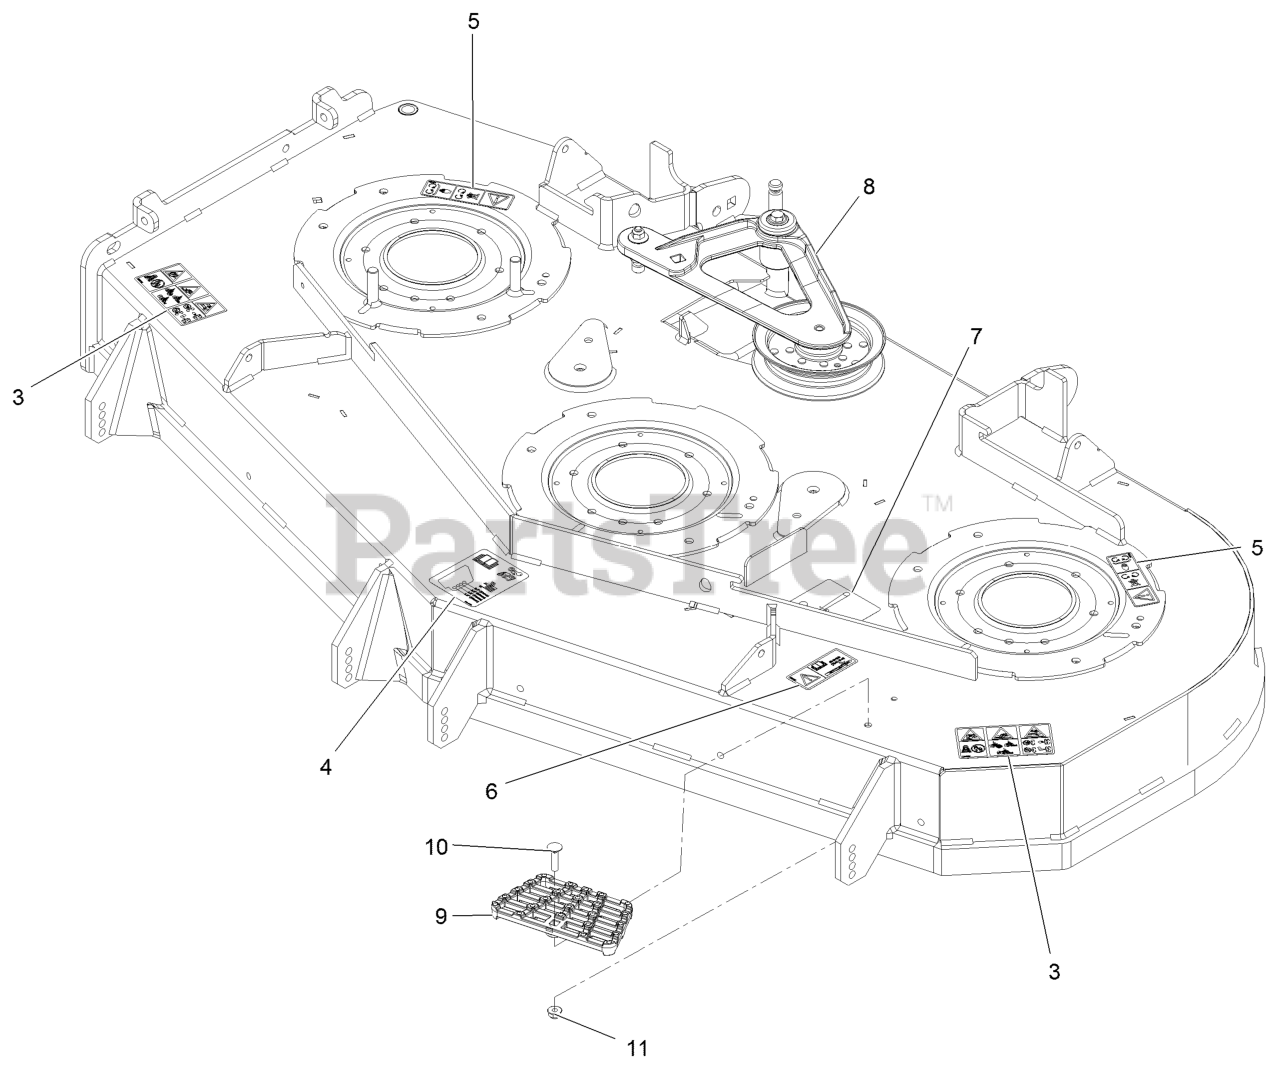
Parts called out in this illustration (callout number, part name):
3	DECAL-DANGER THROWN OBJECTS
4	DECAL-ROLLER, ANTI-SCALP
5	DECAL-COVER, MISSING
6	DECAL-BOLT TORQUE
7	DECAL-BELT ROUTING
8	DECK IDLER ASM
9	STEP-DECK
10	Bolt-Carriage 5/16-18 X 1 1/4
11	NUT-HF, NI
